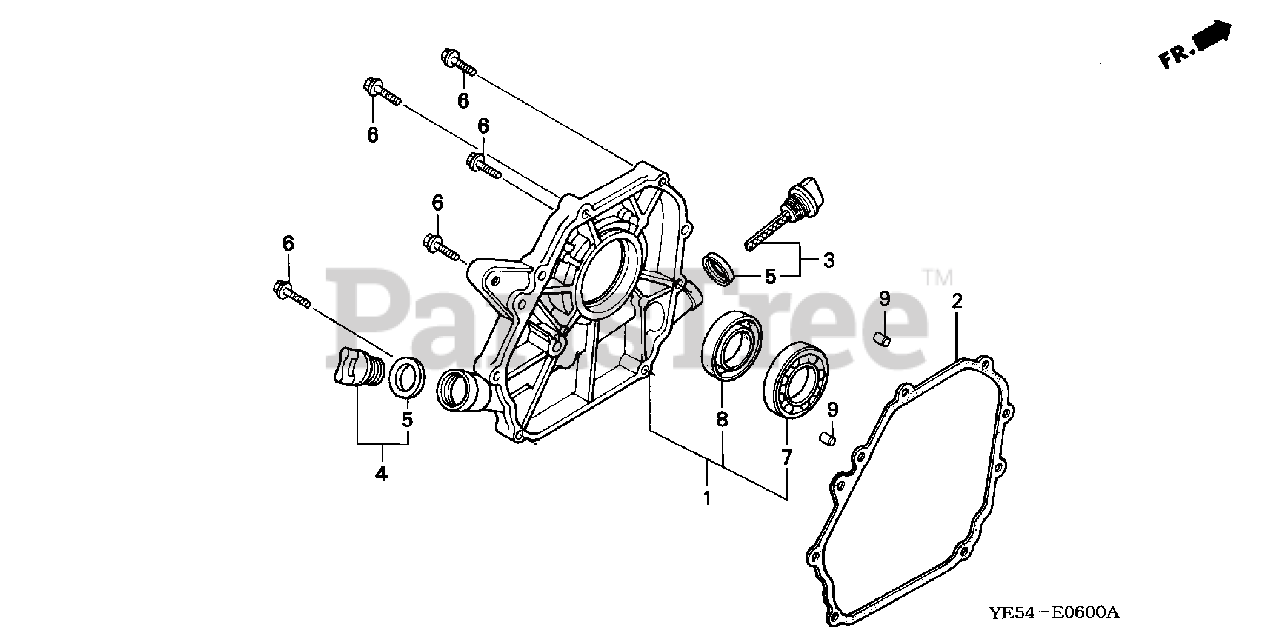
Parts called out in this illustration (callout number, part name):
1	COVER ASSY., CRANKCASE
2	GASKET, CASE COVER
3	CAP ASSY., OIL FILLER
4	CAP ASSY., OIL FILLER
5	GASKET, OIL FILLER CAP
6	BOLT, FLANGE (6X28)
7	BEARING, RADIAL BALL (62/22)
8	OIL SEAL (22X41X6)
9	PIN A, DOWEL (8X14)
